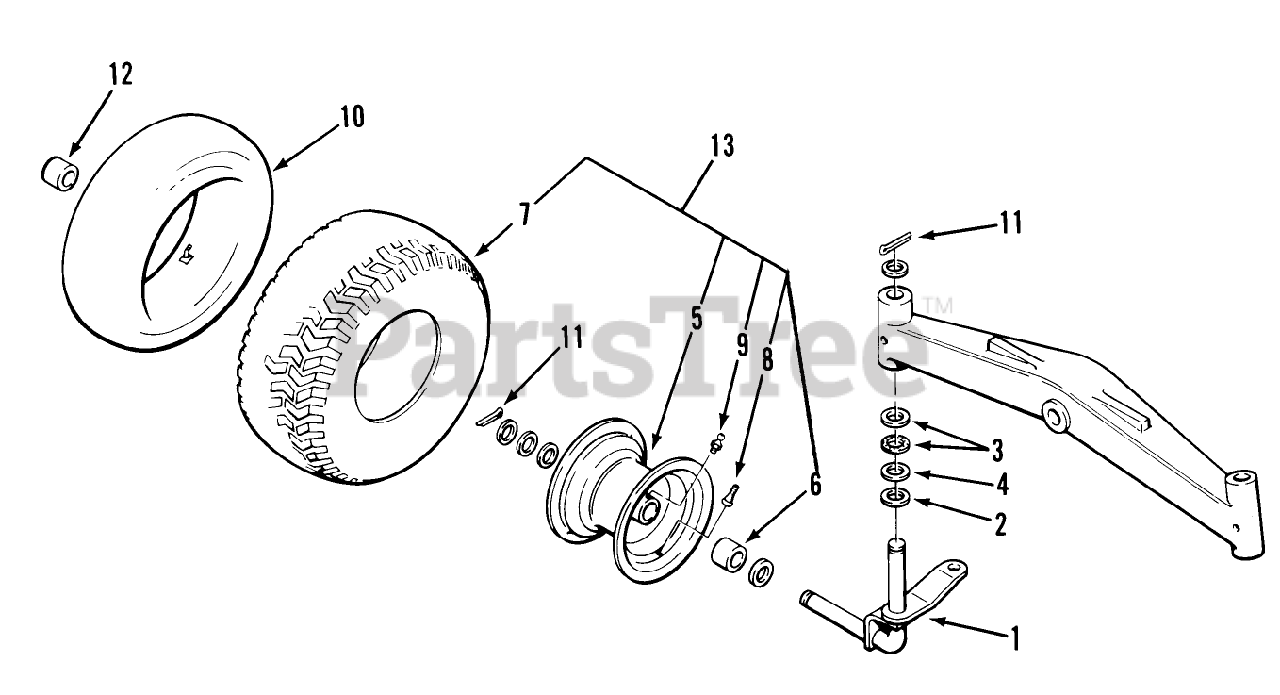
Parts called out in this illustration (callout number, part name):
1	Spindle R.H.
2	Race Thrust
3	WASHER-SLIP
4	WASHER
5	Wheel
6	BEARING-RADIAL FLNGE
7	TIRE TURF SAVER 16X6.50-8
8	VALVE
9	Zerk
10	TUBE-INNER
11	COTTER PIN-4
12	CAP-HUB
13	Wheel and Tire Assembly
